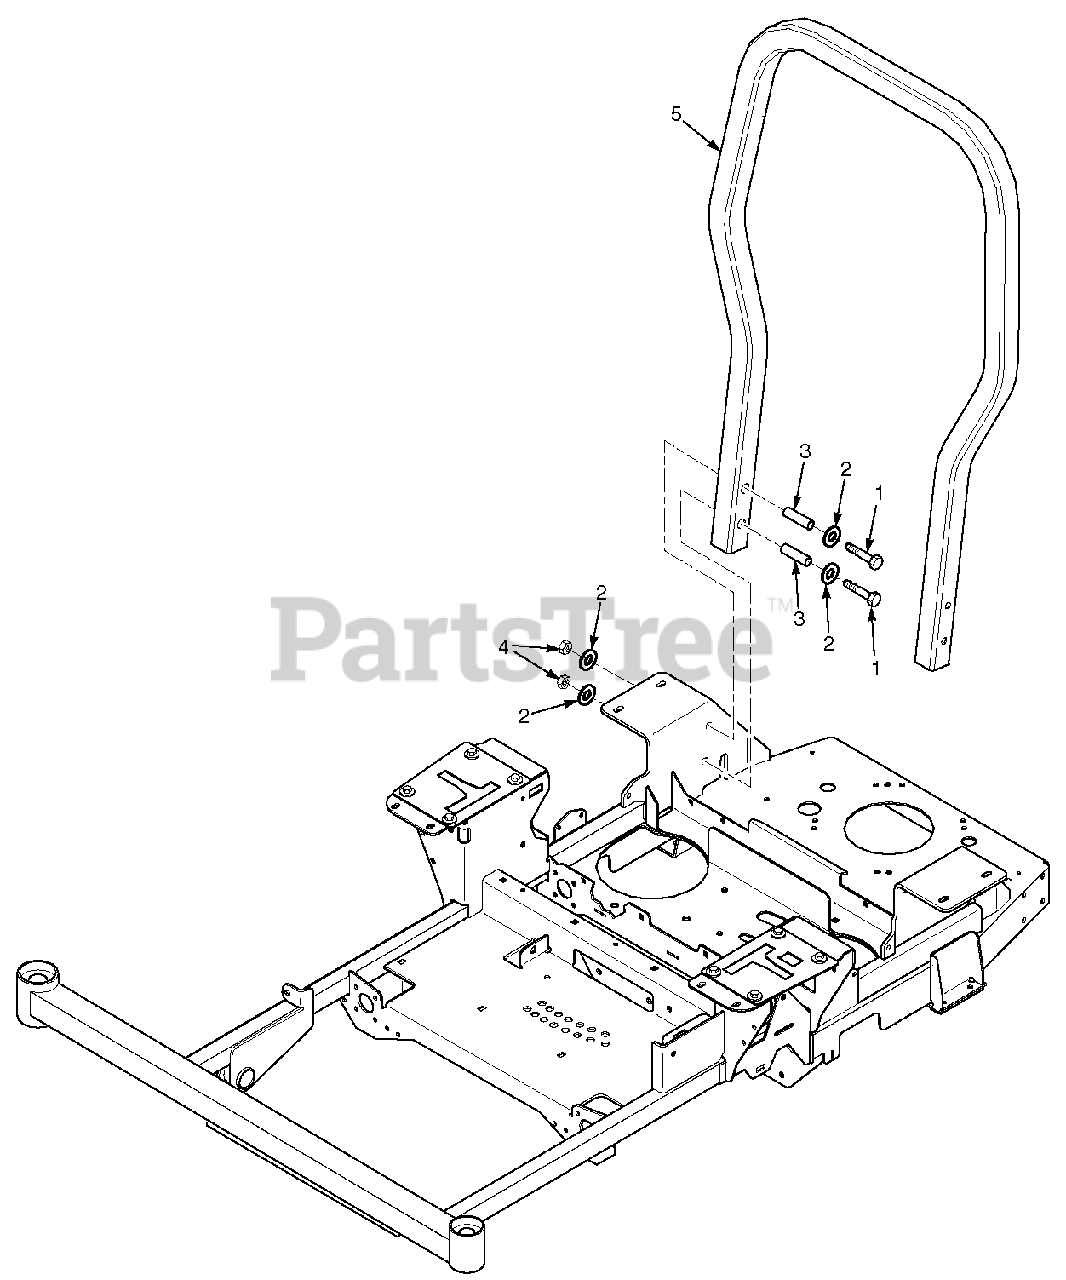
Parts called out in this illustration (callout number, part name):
1	Bolt, Hex Head 1/213 x 3-1/4" Gr. 8
2	Flatwasher, 1/2 - .562 x 1.375 x .109
3	Bushing, SFZ ROPS
4	Nut, Center Lock 1/2-13
5	ROPS
